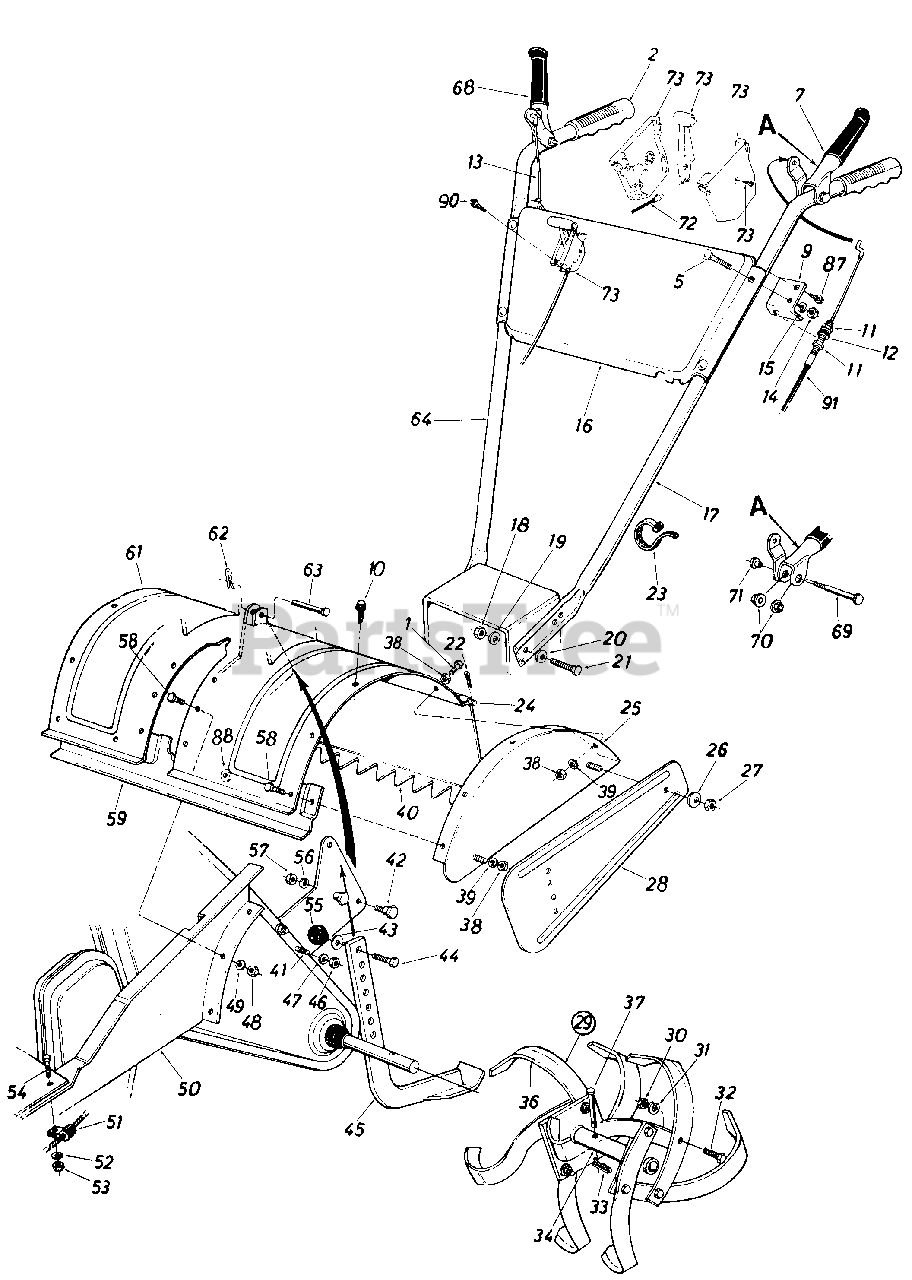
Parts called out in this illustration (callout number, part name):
1	Hex Boit 5/16-18 x 1.25" Lg.*
2	Grip
5	Carr. Bolt 5/16-18 x 1.75"*
7	Clutch Grip Ass'y.-L.H.
9	Clutch Cable Bracket
10	Hex Wash. S-Tap Scr. 5/16-18 x .62" Lg.
11	Hex Nut 5/16-24 Thd.
12	L-Wash. 5/16" I.D.*
13	Tine Clutch Control Cable
14	Hex Nut 5/16-18 Thd.
15	L-Wash. 5/16" I.D.*
16	Handle Panel
17	Handle-L.H.
18	Hex Nut 3/8-16 Thd.
19	L-Wash. 3/8" I.D.*
20	Bell-Wash. 3/8" I.D.
21	Hex Bolt 3/8-16 x 1.00" Lg.
22	Cotter Pin 3/32" Dia. x 3/4"*
24	Tiller Flap Rod
27	Hex Nut 5/16-18 Thd.
30	Hex Nut 3/8-24 Thd.
31	L-Wash. 3/8" I.D.
32	Hex Bolt 3/8-24 x 1.25" Lg.
33	Hairpin Cotter
34	Tine Adapter Ass'y.
37	Clevis Pin 3/8" Dia.
38	Hex Nut 5/16-18 Thd.
39	L-Wash. 5/16" I.D.
40	Tine Shield Flap
41	Hex Bolt 5/16-18 x 1.0" Lg.
42	Shld. Bolt 1/2" Dia. x .426"
43	Fl-Wash. 3/8" I.D. x 5/8" O.D.
44	Hex Bolt 3/8-16 x 3/4" Lg.
46	Hex Nut 5/16-18 Thd.
47	L-Wash. 5/16" I.D.
48	Hex Nut 5/16-18 Thd.
49	L-Wash. 5/16" I.D.*
52	L-Wash. 5/16" I.D.
53	Hex Nut 5/16-18 Thd.
54	Hex Bolt 5/16-18 x 3/4" Lg.
55	Ball Knob 1 1/4" Dia. x 3/8-16 Thd.
56	L-Wash. 3/8" I.D.
57	Hex Nut 3/8-16 Thd.
58	Hex Bolt 5/16-18 x .75" Lg.
59	Bracket Reinforcement
61	Tine Shield Ass'y.
62	Hairpin Cotter
63	Clevis Pin 3/8" Dia.
64	Handle-R.H.
68	Clutch Grip Ass'y.-R.H.
69	Shoulder Bolt .38" Dia. x 1.53" Lg.
70	Hex Flange Plastic Bearing
71	Shoulder Nut 1/4-20 Thd.
72	Throttle Control Wire
73	Throttle Control Box Ass'y.
87	Hex Wash. S-Tap Scr. 1/4-20 x .50" Lg.
88	Bell-Wash. 5/16" I.D.
90	Self-Tap Scr. #10 x 1/2" Lg.
91	Wheel Drive Cable
15390-0498	SHIELD-SIDE - OLD CUB YELLOW (0498)
15390-0499	SHIELD-SIDE - CUB BEIGE (0499)
15390-0629	SHIELD-SIDE - SILVER FLAKE (0629)
15390-0637	SHIELD-SIDE - POWDER BLACK (0637)
15390-0638	SHIELD-SIDE - MTD/TROY-BILT RED (0638)
15390-0648	SHIELD-SIDE - TECH GRAY (0648)
15390-0662	SHIELD-SIDE - OYSTER GRAY (0662)
15390-0665	SHIELD-SIDE - YARDMAN GREEN (0665)
15390-0674	SHIELD-SIDE - YARDMAN YELLOW (0674)
